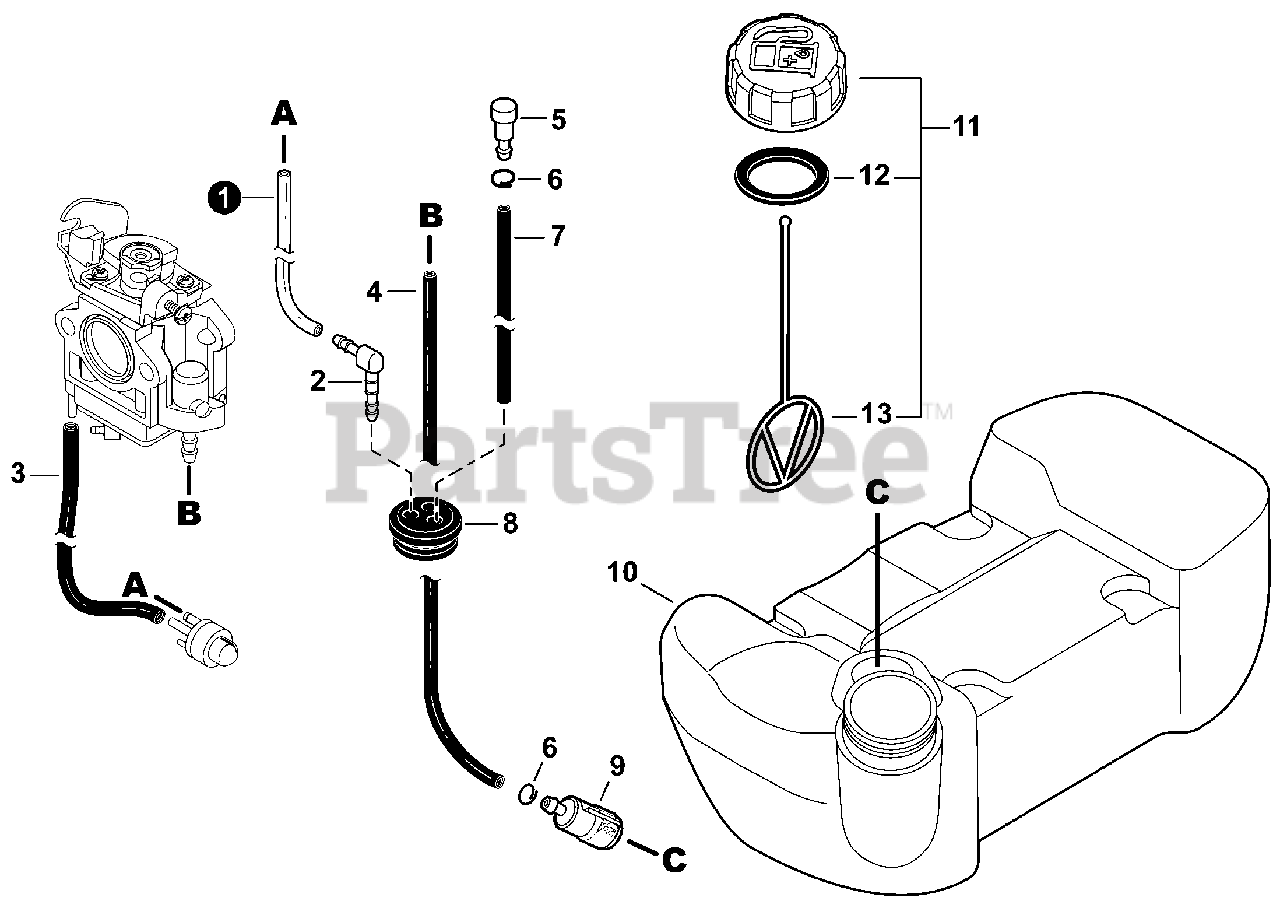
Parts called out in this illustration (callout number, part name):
1	PIPE, FUEL 3×6×60 CLEAR
2	CONNECTOR, PIPE
3	PIPE, FUEL 2.4×5×80 BLACK
4	PIPE, FUEL 3×6×180 BLACK
5	VENT ASSY
6	CLIP Ø6.5 MM
7	PIPE, FUEL 3×6×120 BLACK
8	GROMMET, FUEL
9	FILTER, FUEL
10	TANK, FUEL
11	CAP ASSY, FUEL
12	GASKET, FUEL CAP
13	CONNECTOR, CAP L= 100 MM
